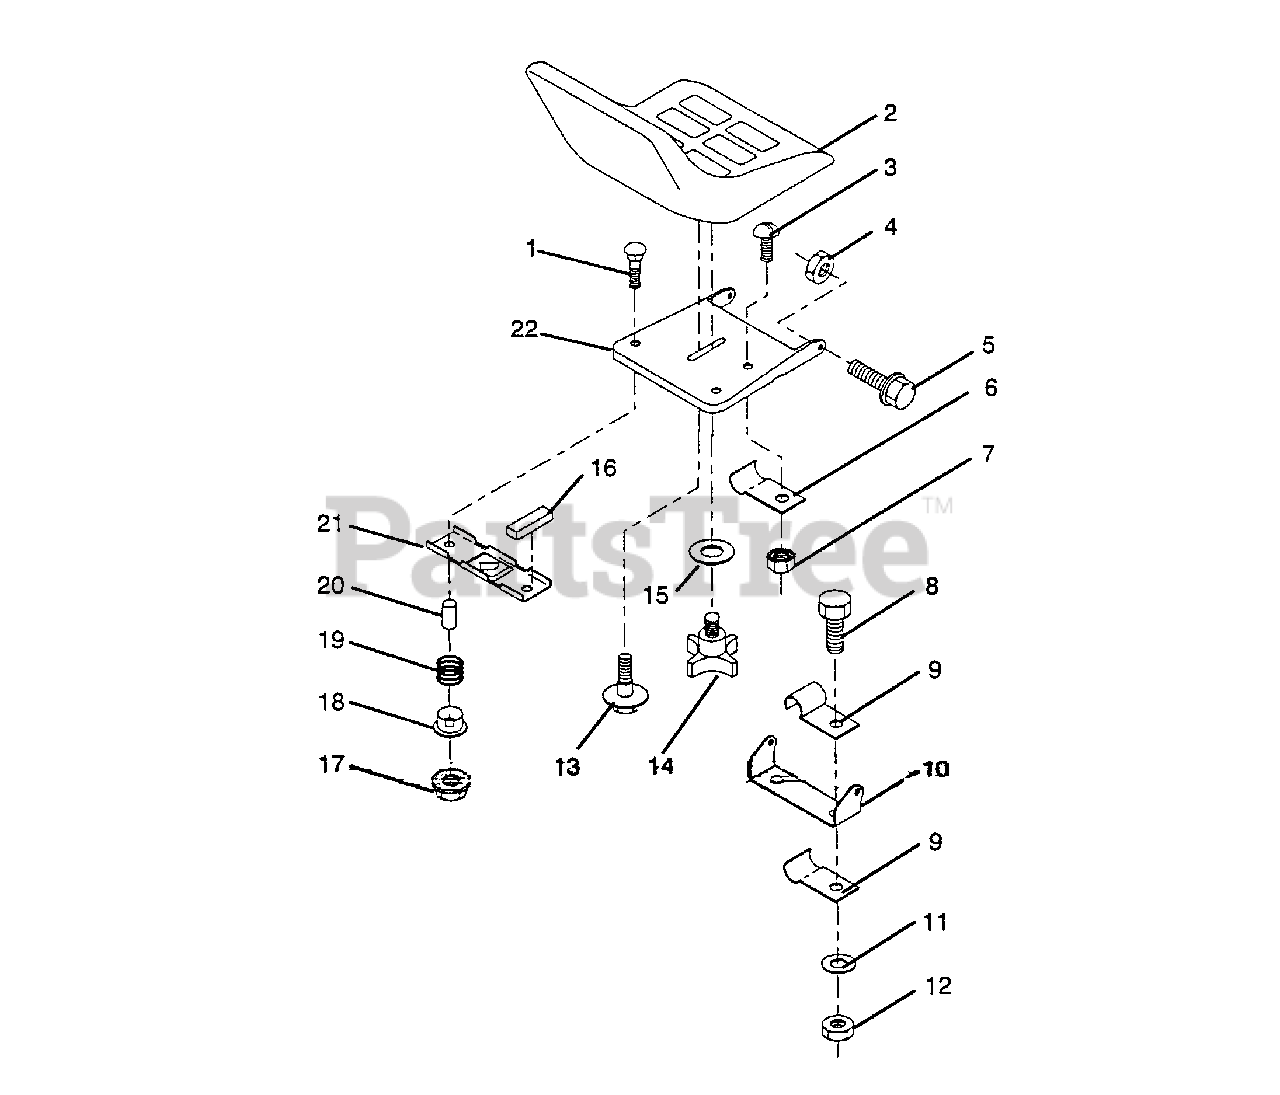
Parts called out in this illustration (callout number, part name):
1	Bolt, Carriage 1/4-20 x 1-1/4
2	Seat
3	Screw, Slotted Pan Head #10-32 x 1/2
4	Nut, Crownlock 5/16-18
5	Bolt, Shoulder 5/16-18 UNC
6	Clip, Insulated
7	Nut, Keps #10-32 UNF
8	Bolt, Fin. Hex 3/8-16 UNC x 3/4
9	Clip, Insulated
10	Bracket, Pivot, Seat
11	Washer 13/32 x 3/4 x 10 Ga.
12	Nut, Crownlock 3/8-16 UNC
13	Bolt, Shoulder
14	Knob, Seat -1/2"
15	Washer 17/32 x 1-3/16 x 12 Ga.
16	Strip, Foam
17	Nut, Hex, Large, Flange Lock
18	Bushing, Snap
19	Spring, Compression
20	Spacer, Split 28 Id. x .88 Large
21	Bracket, Switch, Mounting
